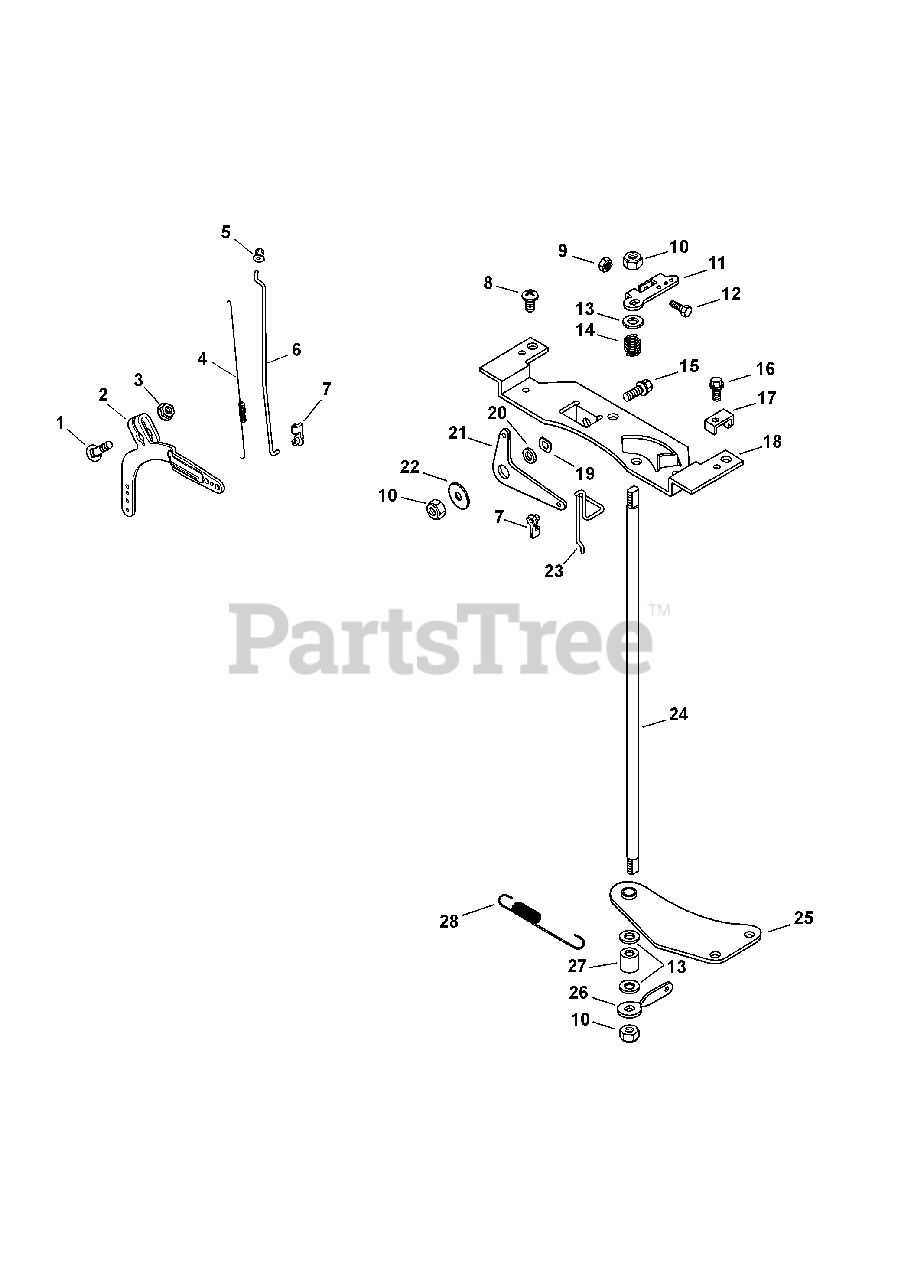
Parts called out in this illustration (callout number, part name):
1	Bolt, M6 x 1.0 x 25
2	Governor Lever
3	Flange Nut, M6 x 1.0
4	Linkage Spring
5	Linkage Retaining Bushing
6	Throttle Linkage
7	Throttle Linkage Bushing
8	Screw, 11-16 x 3/4
9	Nut, M4 x 0.7
10	Lock Nut, M6 x 1.0
11	Throttle Control Lever
12	Cap Screw, M4 x 0.7 x 30
13	Flat Washer, 1/4
14	Throttle Shaft Spring
15	Flange Screw, M6 x 1.0 x 16
16	Flange Screw, M5 x 0.8 x 16
17	Cable Clamp
18	Control Bracket
19	Spring Washer, 3/8
22	Flat Washer, 1/4
23	Choke Linkage
24	Throttle Shaft
25	Throttle Shaft Bracket
26	Throttle Control Lever
28	Governor Spring
